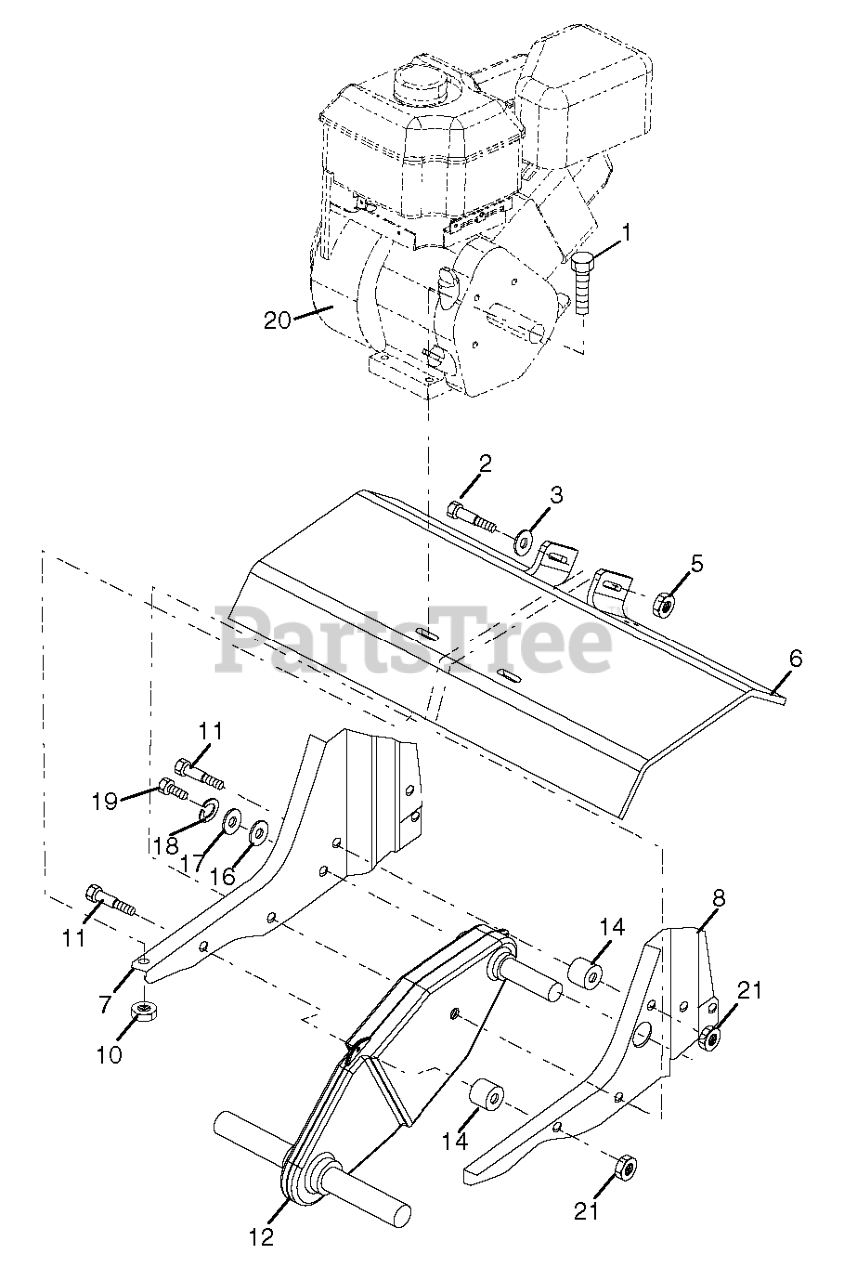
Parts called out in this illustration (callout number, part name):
1	BOLT
2	Bolt, Hex 3/8-16 x 3-1/4
3	WASHER
5	NUT LOCK FLG 3/8-16 UNC
6	SHIELD.PNT.TINE.24".ORANGE
7	BRACKET.ENGINE.RH.TILLER.BLACK
8	BRACKET.ENGINE.TILLER.BLACK
10	LOCKNUT-FLANGE 5/16-18
11	BOLT, HEX HEAD 5/16-18 X 2.5
12	TRANSMISSION.ASM.W/1".D-SHAFT
14	SPACER.SPLIT.327 X 1.00
16	REPL BY 819 09 14-16
18	LOCKWASHER
19	Bolt, Hex 1/4-28 x 3/4 Gr. 5
20	ENGINE LCT, 208CC, TILLER
21	NUT.LOCK.5/16-18
